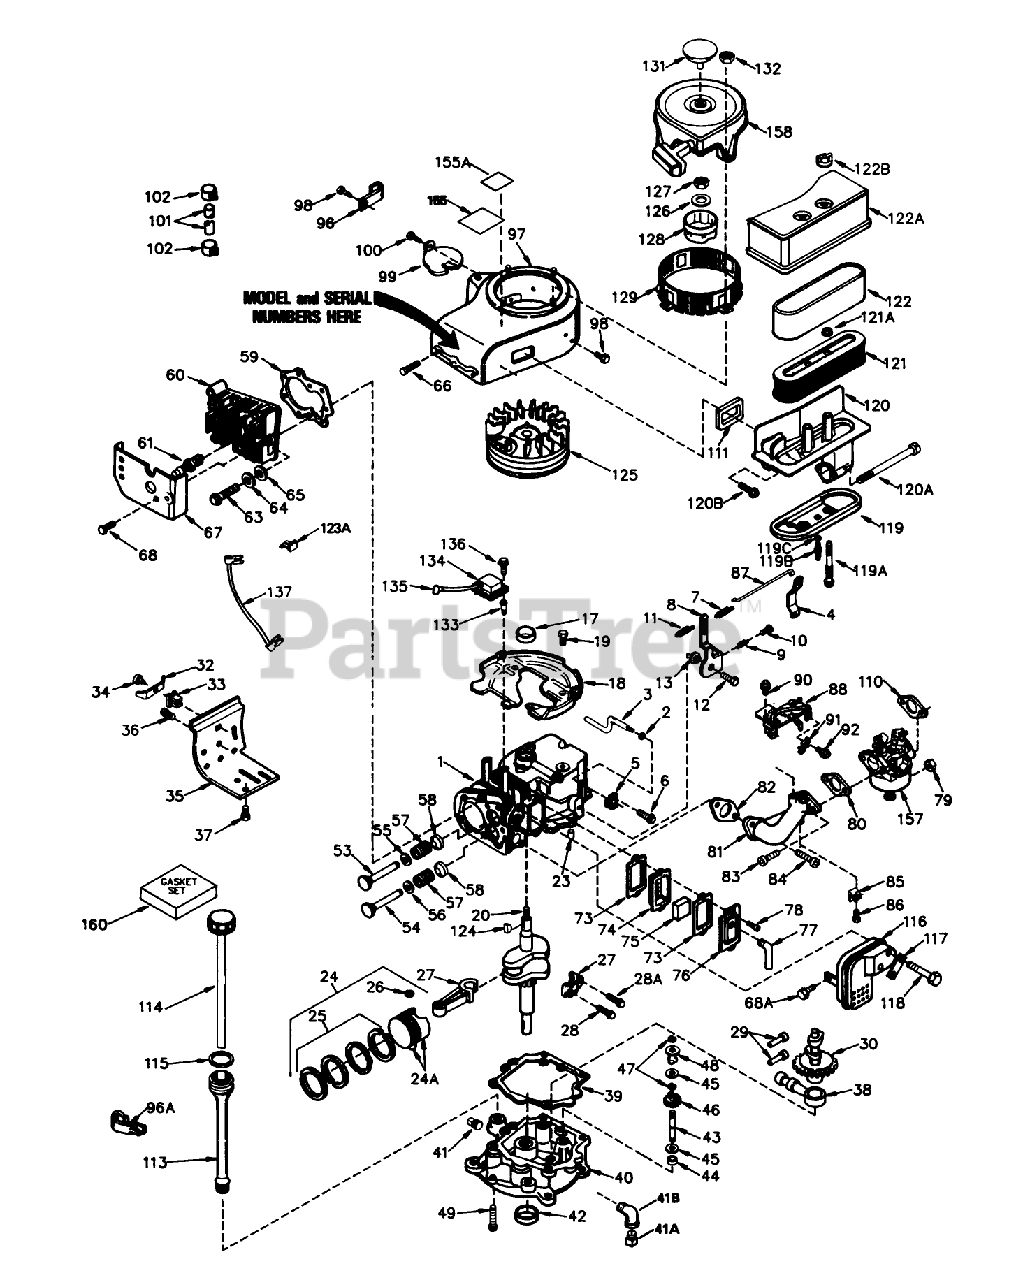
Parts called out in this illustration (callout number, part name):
1	2006A77 WIZARD ROTA
2	Washer-Flat
3	Rod, Governor
4	Governor Lever
5	Clamp-Lever, Governor
6	Screw
7	Spring, Extension
8	Lever, Control (Incl. Ref. #11, 12, 13 110)
9	61709/GIL1515A/95-5
10	Screw
11	Spring, Control
12	SCREW, HEX WASHER HD.
13	Bell crank
17	Seal-Oil
18	Baffle-Blower Housing
19	Screw (1/4-20x19/32)
20	Crankshaft
23	Pin-Dowel
24	Piston, Pin Ring Assy.(Std.) (Incl. Ref. #24A, 25 26)
24	Piston, Pin Ring Assy. (.010 oversize) (Incl. Ref. #24A, 25 26)
24	Piston, Pin Ring Assy. (.020 oversize) (Incl. Ref. #24A, 25 26)
24A	Piston Pin Assy. (Std.) (Incl. Ref. #26)
24A	Piston Pin Assy. (.010 oversize) (Incl. Ref. #26)
24A	Piston Pin Assy. (.020 oversize) (Incl. Ref. #26)
25	Ring Set (Std.)
25	Ring Set (.010" OS)
25	Ring Set (.020" OS)
27	Rod Assy., Connecting (Incl. Ref. #28 28A)
28	Bolt-Rod
28A	Bolt-Rod
29	Lifter-Valve
30	Camshaft (Mechanical Compression Release)
32	Terminal, Ground
33	Grommet
34	Screw (8-32 x 3/8)
35	Extension-Housing, Blower
36	Screw
37	Screw
38	Pump, Oil
39	Cylinder Cover Gasket
40	Flange Assy., Mounting (Incl. Ref.#41, 41A, 42, 43 45)
41	Plug, Drain
41A	Plug, Oil drain
41B	Elbow, 90 Degrees (Can be purchased locally)
42	Seal-Oil
43	Shaft, Governor
44	Spacer Assy. Governor (Incl. Ref. #41)
45	Washer
46	Gear Assy., Governor (Incl. Ref. #45)
47	Ring-Retaining
48	Spool-Governor
49	Screw (1/4-20x1-3/16)
53	Valve, Exhaust (Standard)(Incl. No. 9)
53	Valve, Exhaust (1/32" oversize)(Incl. No. 9)
54	Valve, Intake (Std.) (Incl. Ref. #58)
54	Valve, Intake (1/32" oversize) (Incl. Ref. #58)
55	Cap-Spring, Valve
56	Seal-Intake Valve
57	Spring-Valve
58	Keeper-Spring, Valve
59	Gasket-Cylinder Head
60	Head Cylinder
61	Plug, Spark (Champion RCJ-8)
63	Screw (5/16-18 X 2)
64	Washer-Belleville
65	Washer-Flat
66	Screw (5/16-18x3/4)
67	Cover-Cylinder Head
68	Screw (1/4-20 X 5/8)
68A	Screw (1/2-20x5/8)
73	Gasket-Cover, Valve
74	Body-Breather
75	Element-Breather
76	Cover-Valve
77	Tube-Breather
78	Screw
79	Nut and Lock Washer (1/4-28)
80	Gasket-Carburetor To Intake Pipe
81	Pipe, Intake
82	Gasket-Pipe, Intake
83	Screw (1/4-28x1)
84	Screw (T-30, 5/16-18x1-3/32)
85	Bracket, Intake Pipe
86	Screw (1/4-20 X 5/8)
87	Link, Throttle
88	Bracket Assy., Control
90	Screw (10-24 x 9/16)
91	Conduit
92	Screw (10-32 x 3/8)
96	Clip Oil Tube
96A	Clip, Oil fill tube
97	Housing, Blower
98	Screw
99	Screw
100	Screw (8-32 x 3/8)
101	Line-Fuel
102	Clamp-Line, Fuel
110	Clutch Arm Assembly
111	Gasket, Blower Housing
113	Tube-Fill, Oil
114	Dipstick, Oil
115	O-Ring
116	Muffler Assy.
117	62513 SNWTHWR W/284
118	Screw, Hex Hd.
119	Plate, Support
119A	Screw, Truss Hd.
119B	Fitting, Breather Tube
119C	0 Ring
120	Body, Air Cleaner
120A	Screw, Fil. Hd.
120B	Screw, Hex Washer Hd. Self-drill, Self-tap
121	Element, Air Cleaner (Incl. Ref. #121A)
121A	Nut Lockwasher
122	Filter, Poly Pre-cleaner
122A	Cover, Air Cleaner
122B	Nut, Wing
123A	Clip, Spring
124	Key-Flywheel
125	Flywheel
126	Washer-Belleville
127	Nut-Flywheel
128	Cup-Starter
129	Screen-Starter
131	Plug Starter
132	Nut and Lock Washer (1/4-28)
134	Solid State ASM
135	Cover-Spark Plug
136	Screw
137	Wire, Ground
155	Decal-Instruction
155A	Decal, Instruction
157	Carburetor (Incl. Ref. #80)
158	Starter, Recoil
160	Gasket Set (Incl. items marked *)
